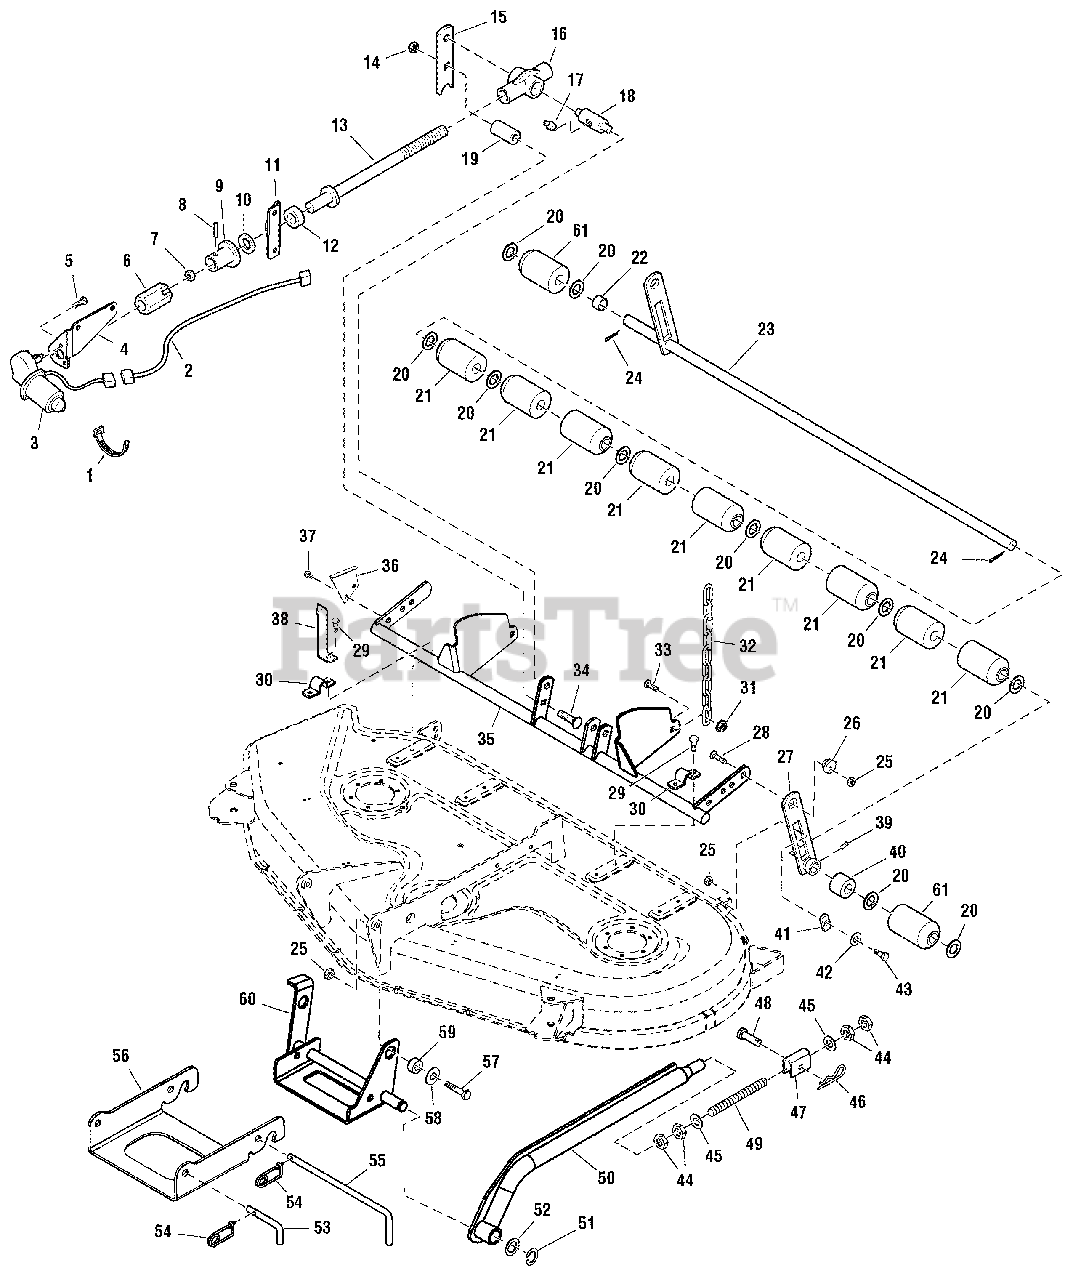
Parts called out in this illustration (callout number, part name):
1	TIE, Self Locking, BLACK
2	HARNESS ASSEMBLY
3	MOTOR, Electric
4	BRACE, Height of Cut
5	CAPSCREW, Hex Washer Head, Dog Point, 1/4-20 x7/8
6	ADAPTER, Motor
7	NUT, Hex, Washer, KEPS, 1/4-20
8	PIN, Spring
10	WASHER, Special, Nylon
11	SUPPORT, Height of Cut
12	BEARING, Thrust
13	ROD & SPACER ASSEMBLY
14	NUT, Hex, Top Lock, 1/2-13
17	FITTING, Lube
21	ROLLER
23	SHAFT & BAR ASSEMBLY
24	PIN, Cotter
25	NUT, Hex Top Lock, 3/8-16
26	NUT, Hex Adjusting, .99 DIA .687
27	BAR & HUB ASSEMBLY
28	CARRIAGE BOLT, 3/8-16 x 1-3/4
29	CAPSCREW, Hex Washer Head, 5/16-18 x 3/4
30	STRAP
31	NUT, Hex Flange Lock, ESNA, 3/8-16
32	CHAIN, 9 Link, 12-1/2" Long
33	CARRIAGE BOLT, 3/8-16 x 1
34	CARRIAGE BOLT, 1/2-13 x 2-1/2
35	SHAFT ASSEMBLY
36	BRACKET, Height of Cut
37	CAPSCREW, Hex Wassher Head, Taptite, 5/16-18 x 1/2
38	INDICATOR, Height of Cut
39	SCREW, Set, Square Head, Cup Point, 5/16-18 x 1/2 G8
42	WASHER, 1/2
43	BOLT, Shoulder, 3/8-16 X 1.34
44	NUT, Hex, Jam, 5/8-18
45	WASHER, 5/8
46	CLIP, Hair Pin
48	PIN, Yoke, Drilled, 1/2 x 2
49	STUD, 5/8-18 x 8-9/16
50	ARM & TUBE ASSEMBLY
51	RING, Retaining, External, 1
52	WASHER,1
54	PIN, Spring
57	CAPSCREW, Hex Head, 3/8-16 x 1-3/4
58	WASHER, 3/8
60	HITCH ASSEMBLY
